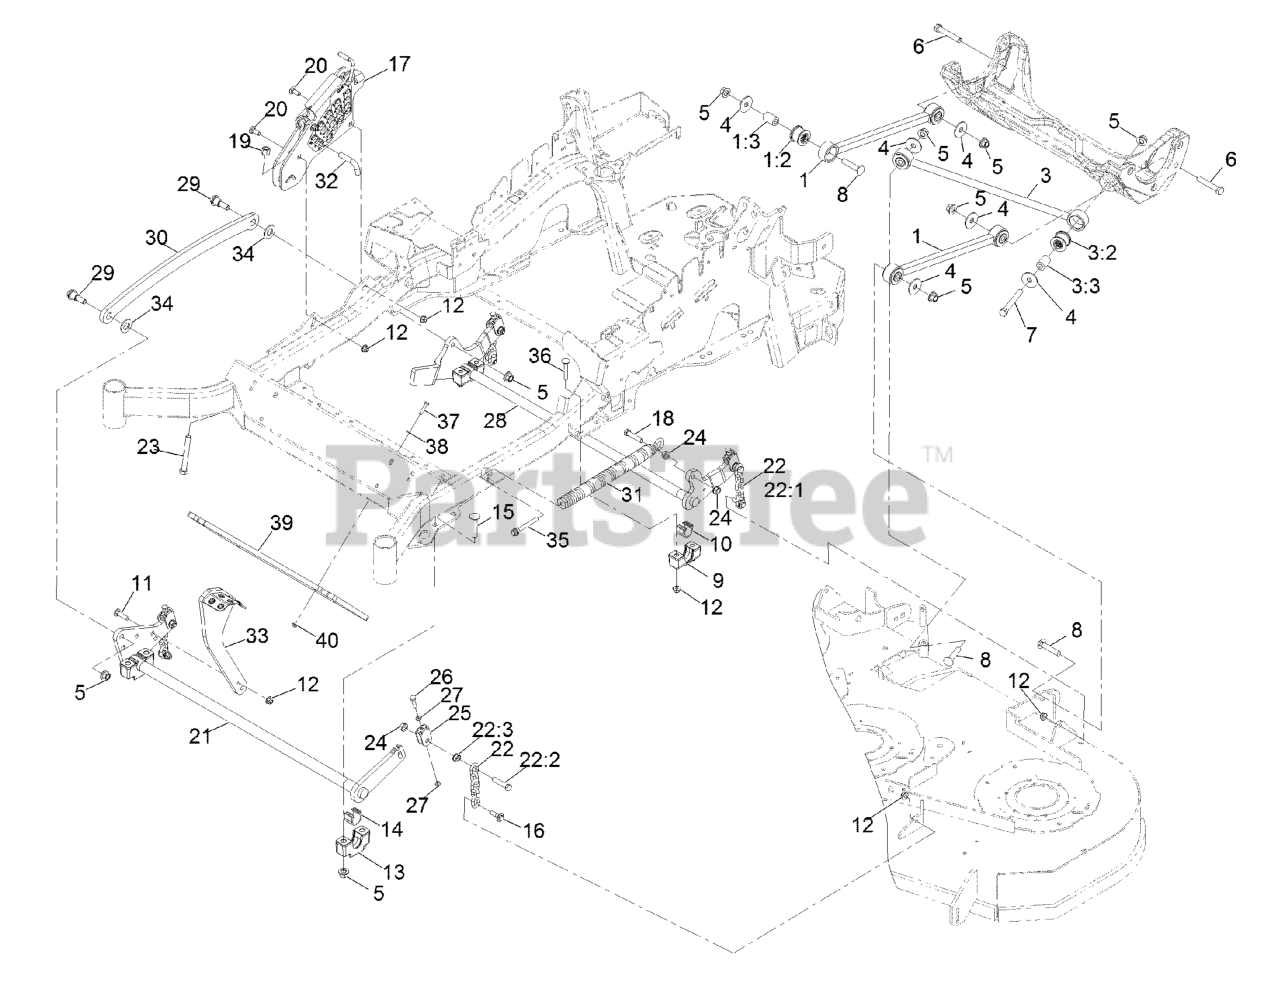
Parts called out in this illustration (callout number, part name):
1	LONG STRUT ASM
1:2	BUSHING-SUSPENSION, RUBBER
3	PANHARD ROD ASM
3:2	BUSHING-SUSPENSION, RUBBER
4	WASHER-THRUST
5	Nut-Lock 1/2-13
6	SCREW-HH
7	SCREW-HH
8	SCREW-CARR
9	SUPPORT-CROSS SHAFT, BEARING REAR
10	BEARING-CROSS SHAFT, REAR
11	SCREW-CARR
12	NUT-HF, NI
13	SUPPORT-CROSS SHAFT, BEARING
14	BEARING-CROSS SHAFT, FRON
15	Bolt-Carriage 1/2-13 X 2 1/2 Spl Neck
16	SCREW-SHOULDER, HHF
17	HOC ASM
18	SCREW-HH
19	NUT-LOCK, NI
20	BOLT-CARR
21	DECKLIFT-FRONT
22	DECK LIFT CHAIN ASM
22:1	CHAIN-LIFT, DECK
22:2	SCREW-HH
23	BOLT-TAP
25	YOKE-ADJUST, DECK
26	SCREW-HH
27	NUT-JAM
28	LIFT-DECK, REAR
29	SCREW-SHOULDER, HHF 1/2-13 X 1.12
30	LINK-LIFT, DECK
31	SPRING-EXTENSION
32	PIN-HOC
33	LEVER-FOOT
34	WASHER-FLAT
35	BOLT-SHOULDER
36	Bolt-Carriage 3/8-16 X 2 1/4
37	SCREW-HH
38	WASHER-FLAT
39	WEIGHT-TOE BOARD
